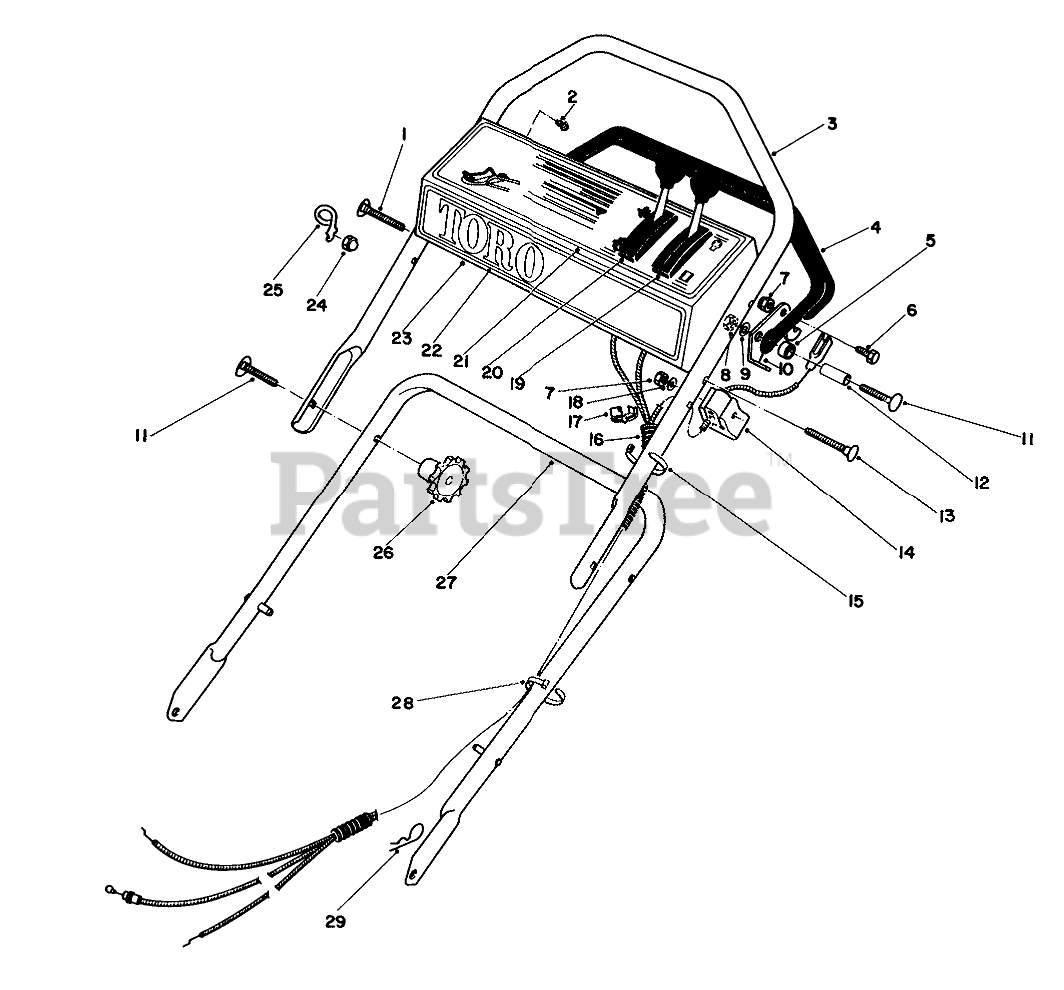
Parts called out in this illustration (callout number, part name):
1	HANDLE SCREW
2	SCREW-HWHTF
3	UPPER HANDLE
4	Bar-Control
5	Nylon Spacer
6	SCREW-HH
7	NUT-LOCK, NI
8	NUT-LOCK, NI
9	WASHER-PLAIN
10	Lever-Control
11	5/16-18 X 2 HNDLE SCREW
12	Spacer
13	SCREW-HANDLE
14	SUPPORT-CABLE
15	TIE-CABLE
16	CONT. CABLE COVER
17	FITTING-RING
18	WASHER-FLAT
19	SERVICE TRACT. CONTROL
20	CHOKE CONTROL
21	Decal-Instructions
22	Decal-Toro
23	Panel-Control (Incl. Ref. #21)
24	NUT-CAP
25	Guide
27	LOWER HANDLE ASSEMBLY
28	TIE-CABLE
29	PIN-COTTER, HAIR
